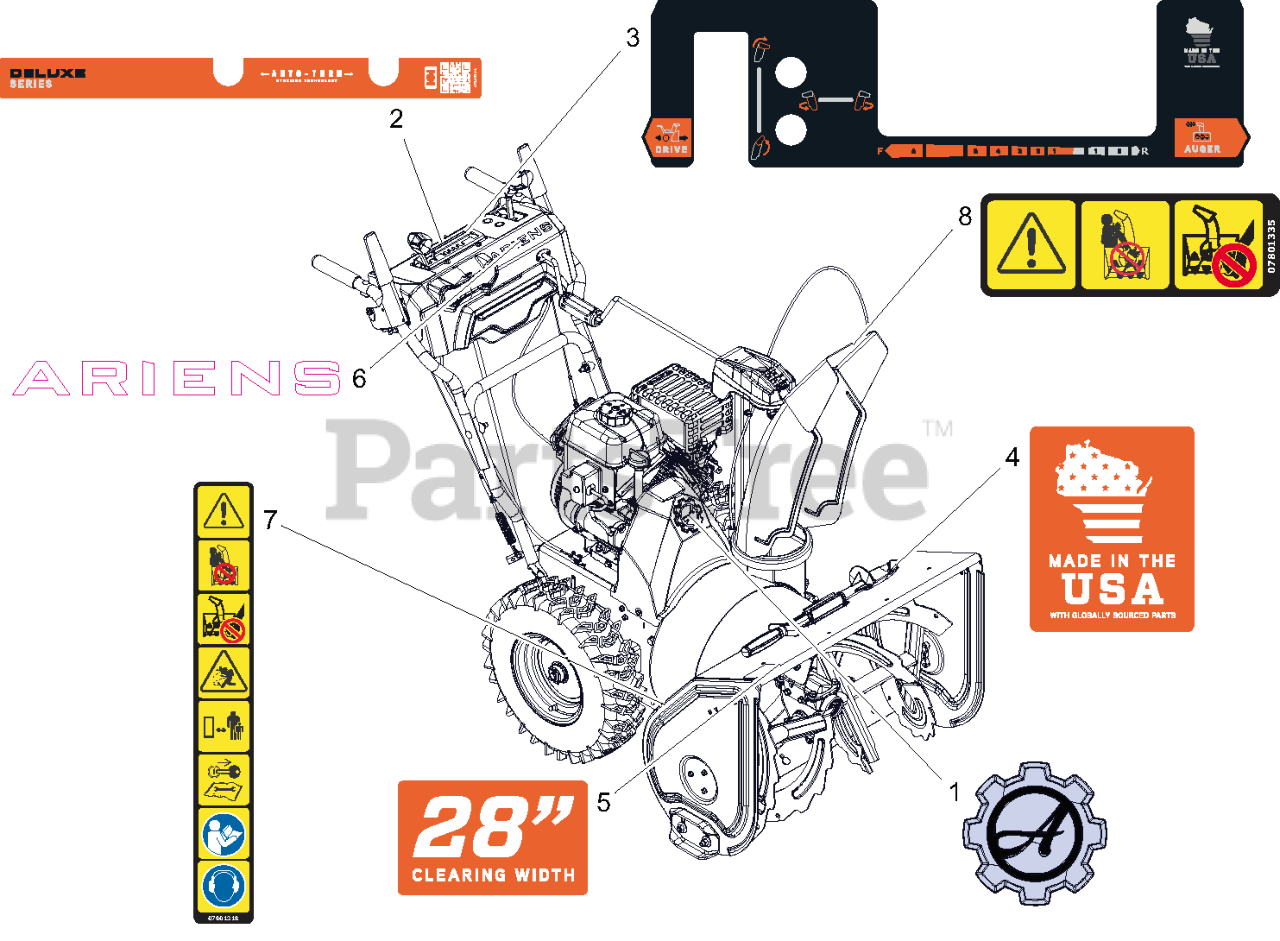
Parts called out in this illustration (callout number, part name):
1	DECAL, ARIENS - GEAR BADGE
2	DECAL- DASH - DELUXE
3	DASH- CONTROL - SMALL DASH
4	DECAL- MADE IN USA
5	DECAL- CLEARING - 28
6	DECAL- ARIENS - 7.46"
7	DECAL- SAFETY - DANGER
8	DECAL- DANGER
